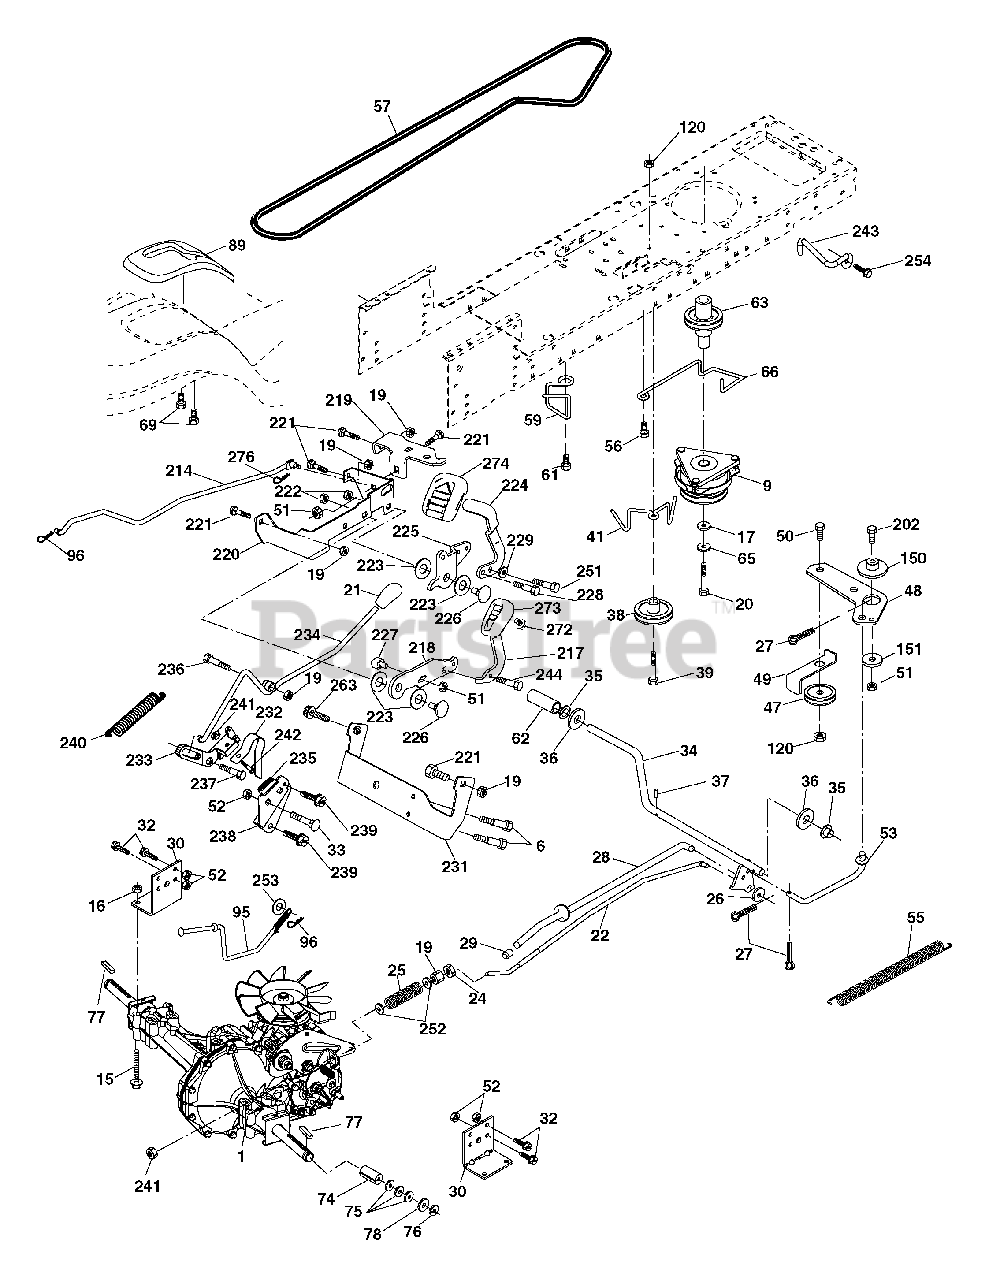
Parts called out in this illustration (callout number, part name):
1	Transaxle Hydro gear Model 347-0510 (See Breakdown)
6	Screw 5/16-18 x 3/4
9	Clutch Elec
15	Bolt Hex Flghd 5/16-18 Gr. 5
16	Nut Lock Hex W/Ins. 5/16-18 unc
17	Washer 1-1/2 OD x 15/32 ID x .250
19	Nut Lock Hex W/Wsh 3/8-16 unc
20	Bolt Hex 7/16-20 x 4 x Gr. 5-1.5
21	Knob Custom Control Cruise
22	Rod, Brake
24	Nut, Hex Jam 3/8-16 unc
25	Spring, Brake Rod
26	Washer
27	Pin Cotter 1/8 x 3/4 CAD.
28	Rod, Parking Brake
29	Cap Brake Parking
30	Bracket, Transaxle
32	Bolt Hex Hd 5/16-18 unc x 3/4
33	Bolt Rdhd Sqnk 5/16-18 unc x 3/4
34	Shaft, Foot Pedal
35	Bearing, Nylon
36	Washer
37	Pin, Roll
38	Pulley, Composite, Flat
39	Bolt Rdhd 3/8-16 unc x 2-3/4 Gr. 5
41	Keeper, Belt Idler Flat
47	Pulley, Idler, V-Groove
48	Bellcrank Clutch Grnd Drw Stl
49	Retainer, Belt
50	Bolt Carr Sh 3/8-16 x 1-1/2 Gr. 5
51	Nut Crownlock 3/8-16 unc
52	Nut, Crownlock 5/16-18 unc
53	Link, Clutch
55	Spring, Return, Clutch
56	Screw 3/8-16 x 1-1/4
57	V-Belt, Ground Drive
59	Keeper, Center Span
61	Screw 3/8-16 x .875
62	Cover, Pedal
63	Pulley, Engine
65	Washer
66	Keeper Belt Engine
69	Screw Hex Wsh Hi-Lo 1/4-1/2 unc
74	Spacer, Axle
75	Washer 25/32 x 1-1/4 x 16 Ga.
76	E-Ring
77	Key, Square
78	Washer 25/32 x 1-5/8 x 16 Ga.
89	Console, Shift
95	Rod Bypass
96	Retainer Spring 1" Zinc/Cad
120	Nut Lock Flg 3/8-16 unc
150	Spacer Retainer
151	Washer 13/32 x 2 x 10 Ga.
202	Bolt RDHD 3/8-16 unc x 1-3/4 Gr. 5
214	Link Transaxle
217	Pedal Reverse
218	Arm Control Pedal Reverse
219	Bracket Frest Pdl Ctrl. Hyd
220	Bracket Mtg. Pedal Control
221	Bolt Rdhd Sqnk 3/8-16 unc x 3/4
222	Nut Crownlock 7/16-14 unc
223	Washer Nylon 11/16 ID x .060
224	Pedal Forward
225	Arm Control Pedal Forward
226	Bolt Pivot Spacer
227	Cam Reverse Pedal LT
228	Bolt Shoulder 5/16-18
229	Washer Serrated 5/16 x .75
231	Strap Torque
232	Actuator Cruise Disengage
233	Pawl Control Cruise
234	Lever Control Cruise
235	Sector Control Cruise
236	Bolt Shoulder 3/8-16 unc 1/44
237	Bolt Shoulder 5/16-18
238	Arm Mtg. Cruise Sector
239	Screw Thdrol 5/16 x 1/2
240	Spring Return Cruise Control
241	Nut Centerlock 1/4-20 unc
242	Bolt Fin Hex 1/4-20 x .75
243	Bracket Anti-Rotation
244	Screw 5/16-18 x 5/8
251	Screw 5/16-18
252	Washer 13/32 x 1 x 16 Ga.
253	Washer .3125 x .615 x 16 Gr.
254	Screw 3/8-16 x 1
263	Screw 3/8-16 x .75
272	Screw, 5/16-18 x 1/2 TT
273	Pad, Reverse Pedal
274	Cover Pedal Forward
276	Clip Retainer .0375
